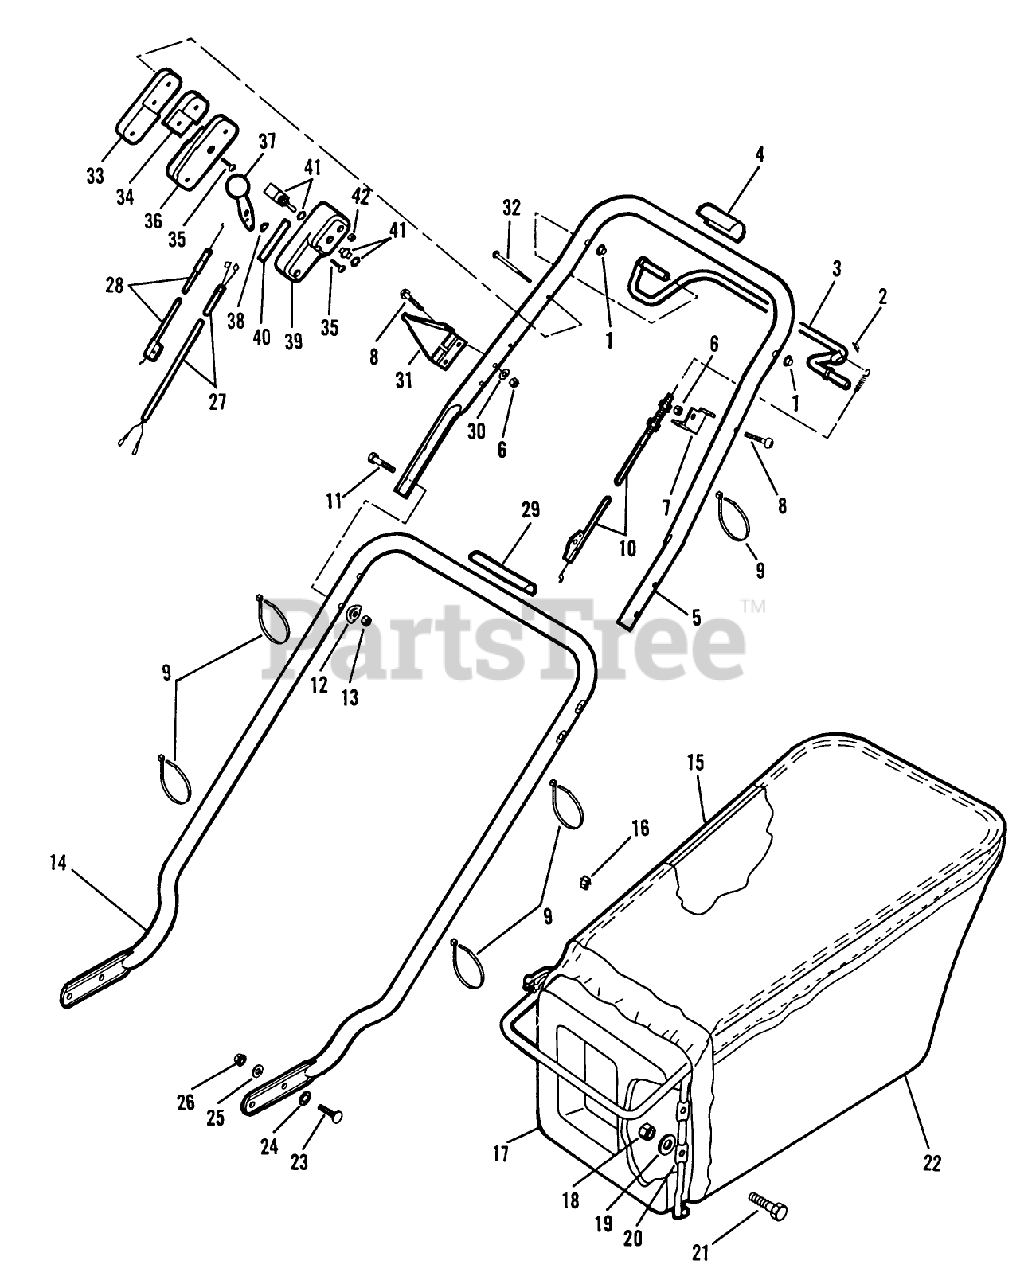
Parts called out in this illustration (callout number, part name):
5	UPPER HANDLE *
6	LOCKNUT E
7	ANCHOR C'DUIT TRO
10	CONTROL CABLE WES
12	WASHER-CURVED
13	NUT-LOCK F
14	LOWER HANDLE *G
15	HANGER BAG TROX
16	S CLIP ARDEN
17	BAG ADAPTOR PL
18	LOCKNUT E
19	WASHER
20	LATCH BAR AY ARGO
25	WASHER
28	THROTTLE CABLE
30	WASHER
32	SCREW
33	OUTER CONTROL CASE
35	SCREW
37	LEVER&KNOB AY WES
38	WASHER-SPRING
42	NUT C/LOCK E
